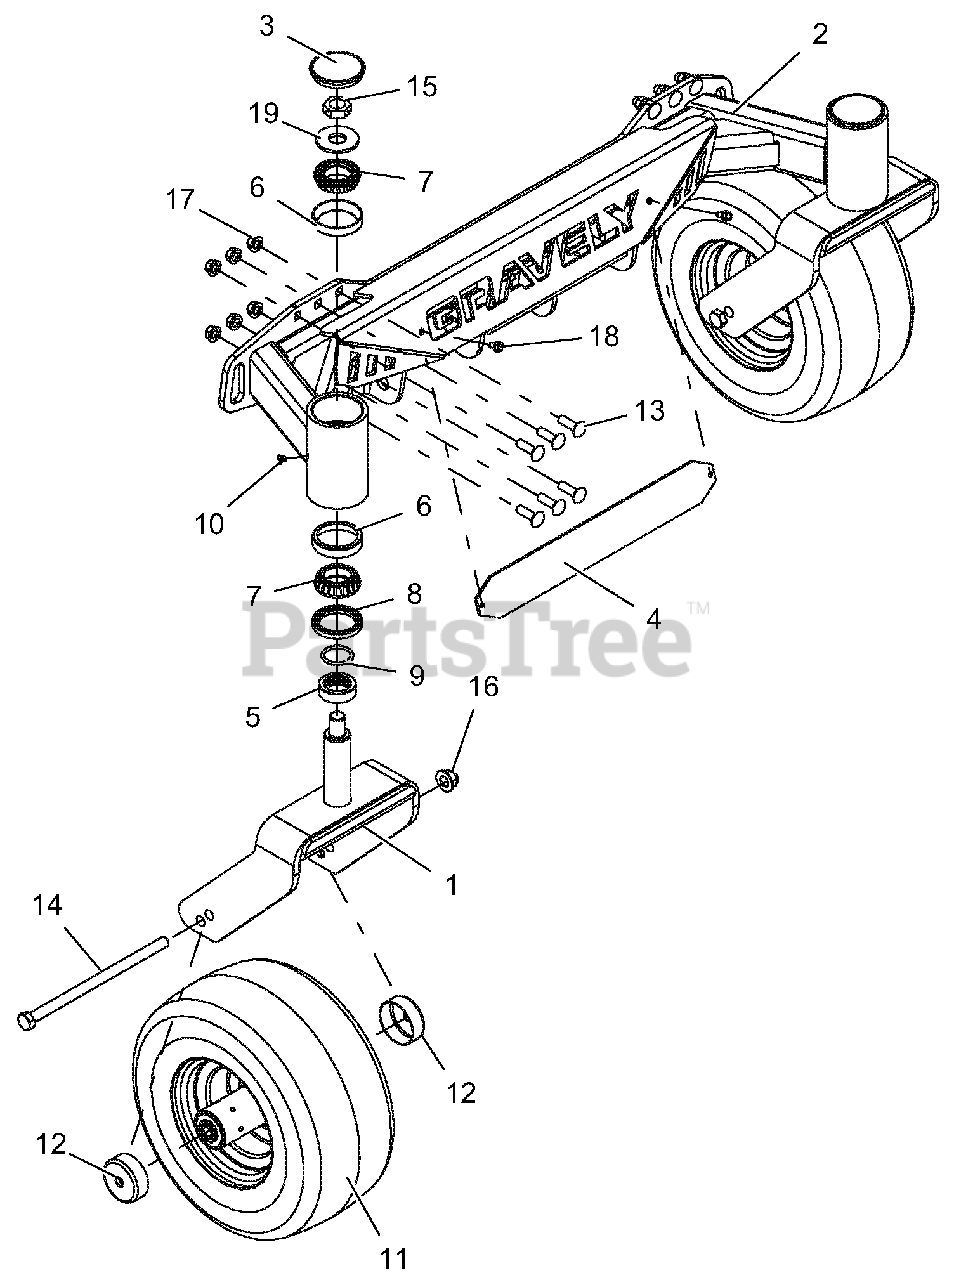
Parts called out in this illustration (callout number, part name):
1	WMT, CASTER FORK - RED
2	WLDMT, FRONT AXLE
3	CAP, DUST
4	PLATE, BACK NAME-BLACK
5	SPCR, FRONT CASTER FORK
6	BRG, CUP 2.328 X .465
7	BRG, CONE 1.250 X .660
8	SEAL, OIL 1.75 X 2.332 X .312
9	O-RING, .139 W X 1.234 ID
10	PLUG, .250-28 X .185 HEX HEAD
11	TIRE/WHEEL, 13 X 6.50-6 SEMI PNEU
12	SHIELD, WHEEL BEARING
13	BLT-RDHDSQNK .38-16X1.25 G5 YWZC
14	BLT-HEX .50-13X9.00 GR5 YWZC
15	@NUT-LK-CTR-JAM .75-16 YWZC
16	NUT-LK-NYL-FLG .50-13 YWZC
17	NUT, LK-TOP-FLG .38-16 YWZC
18	SCR-TAP .25-20X.50 HWH TR YWZ
19	WSHR-FL-STL.812X2.00X.148YWZC
